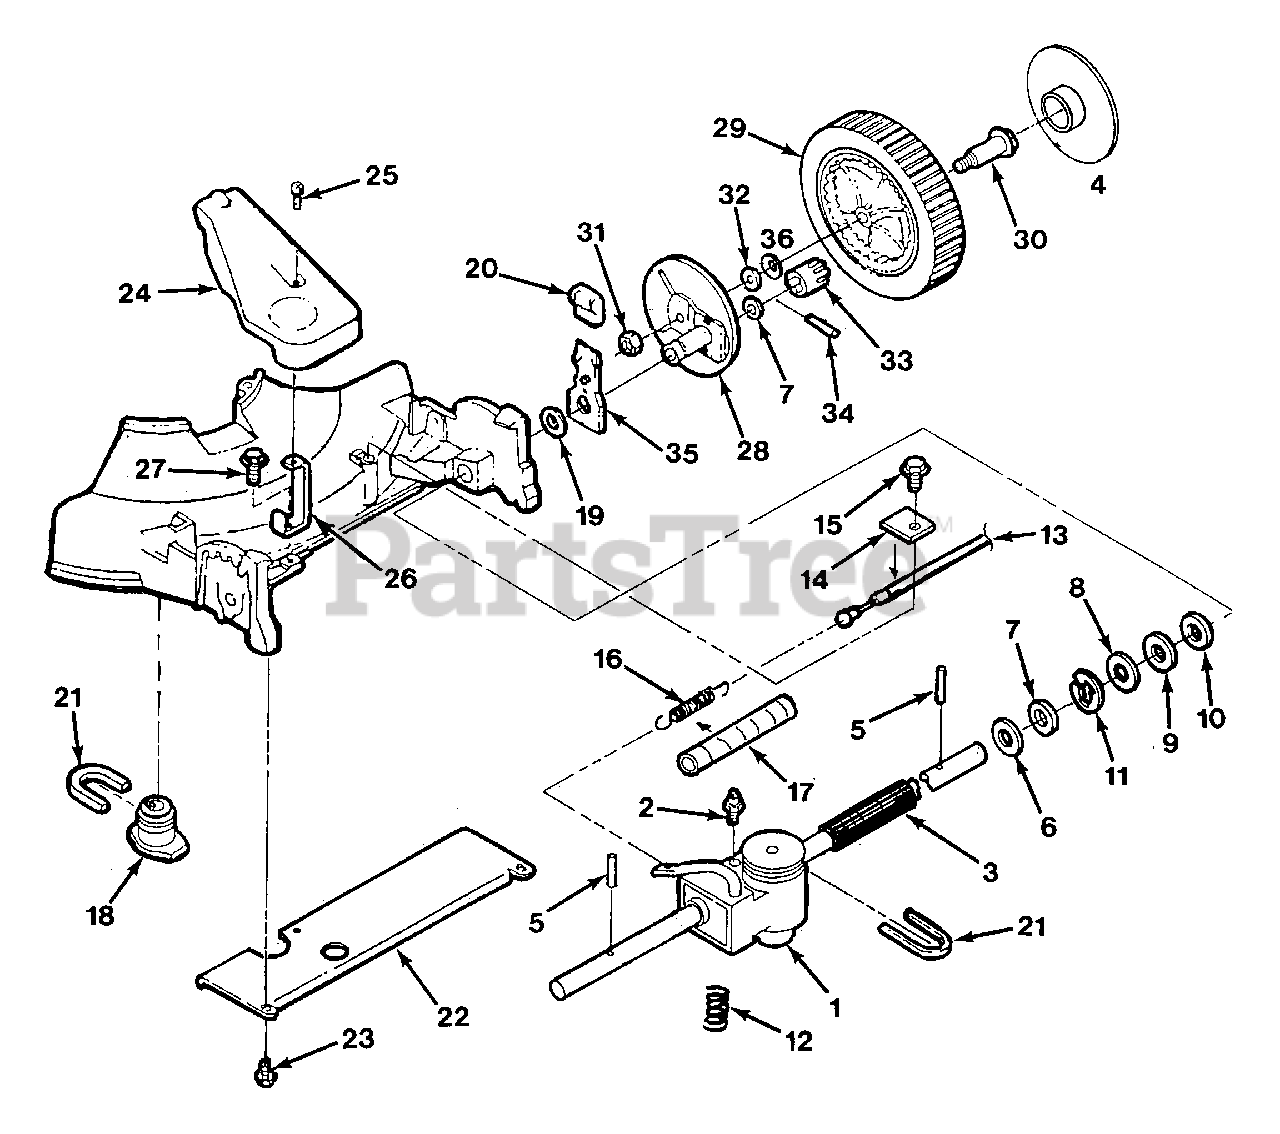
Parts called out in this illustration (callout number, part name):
1	Transmission - one speed
2	Vent - Transmission
3	Cover - axle, long
5	Pin - roll 1/8 x 7/8
6	Washer - flat
7	Washer - flat 1/2
8	Washer - flat 1
9	Washer - shim 1
10	Washer - wave
11	Ring - retainer
12	Spring - compression
13	Cable - ground drive
14	Clamp - drive cable
15	Screw - hex 1/4-20 x 1/2 tap
16	Spring - extension
17	Cover - spring
18	Adapter - blade w/pulley
19	Spacer - adjuster lever
20	Tip - adjuster lever
21	Belt - drive
22	Cover - rear
23	Screw - hex 1/4-20 x 3/4
24	Cover - gear reducer
25	Screw - phillips 1/4-20 x 3/4
26	Bracket - cover
27	Screw - hex 1/4-20 x 9/16 tap
28	Support - drive wheel
29	Wheel - 8" w/tire
30	Bolt - wheel 3/8-16
31	Nut - hex 3/8-16 flnge lock
32	Washer - flat
33	Pinion - drive RH
34	Pin - drive
35	Lever - height adjuster, rear
36	Washer - Belleville
